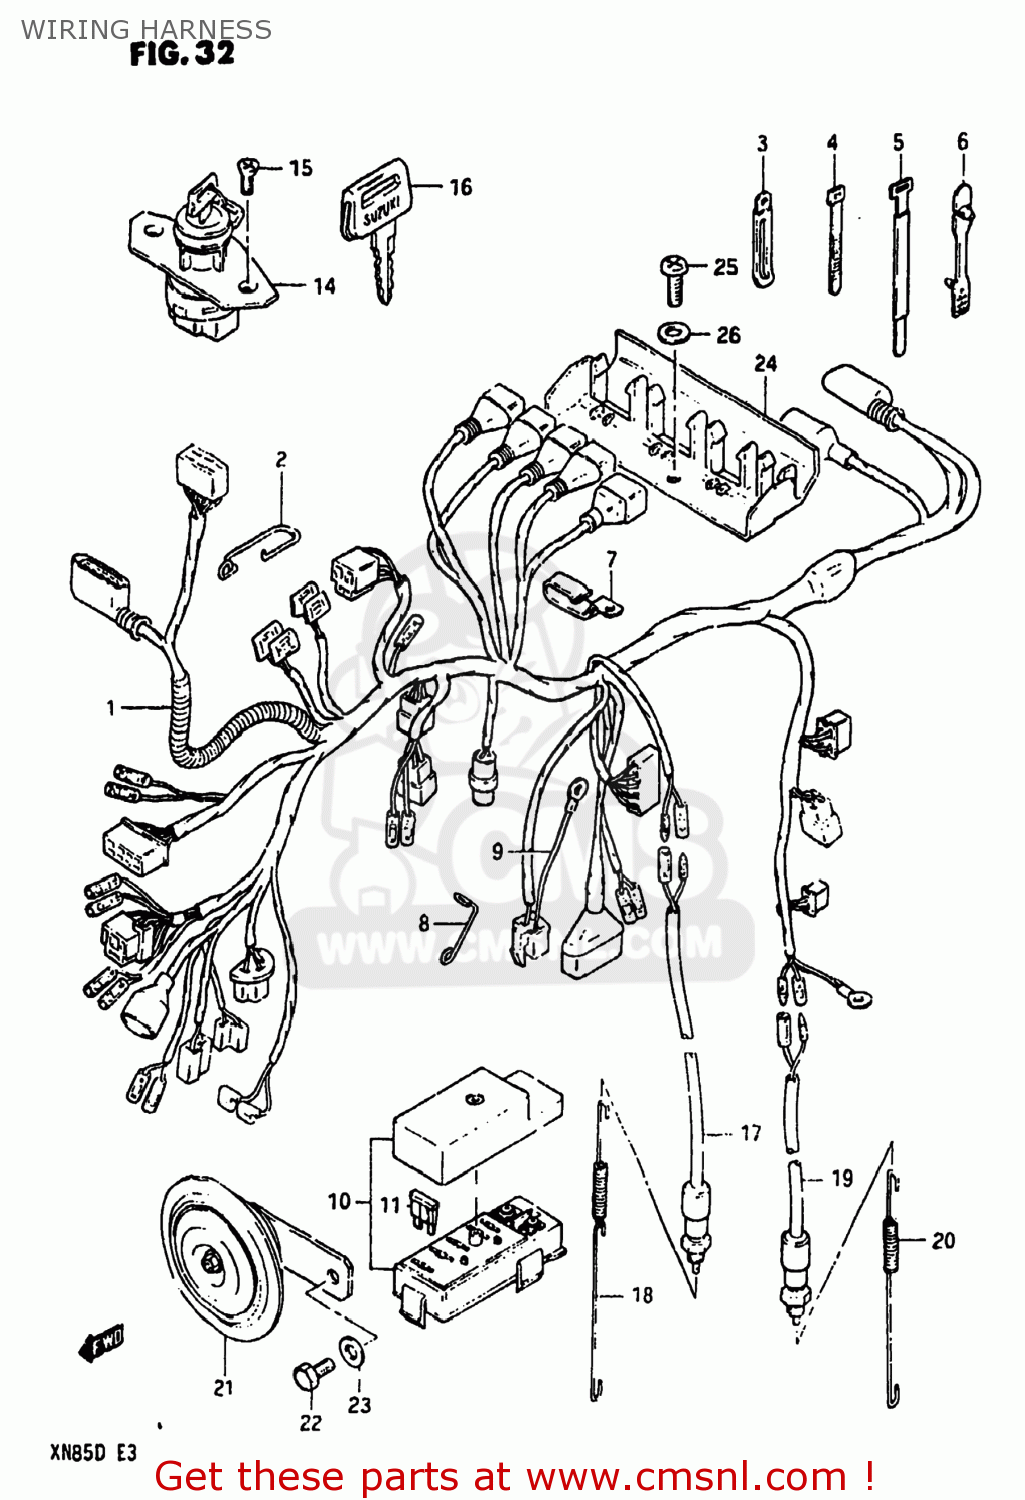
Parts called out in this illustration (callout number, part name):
1	HARNESS,WIRING
2	BOOT,WIRING HARNESS
3	CLAMP
4	CLAMP(L:80)
5	CLAMP
6	CLAMP,L:88
7	CLAMP
8	GUIDE,WIRING HARNESS
9	WIRE
10	BOX ASSEMBLY,FUSE
11	FUSE(10A)
12	SCREW
13	WASHER
14	SWITCH ASSEMBLY,IGNITION
15	SCREW
16	KEY,BLANK
17	SWITCH ASSEMBLY,STOP LAMP
18	SPRING
19	SWITCH ASSEMBLY,SIDE STAND
20	SPRING
21	HORN ASSY
22	BOLT 8X12
23	WASHER
24	HOLDER, COUPLER
25	SCREW
26	WASHER
